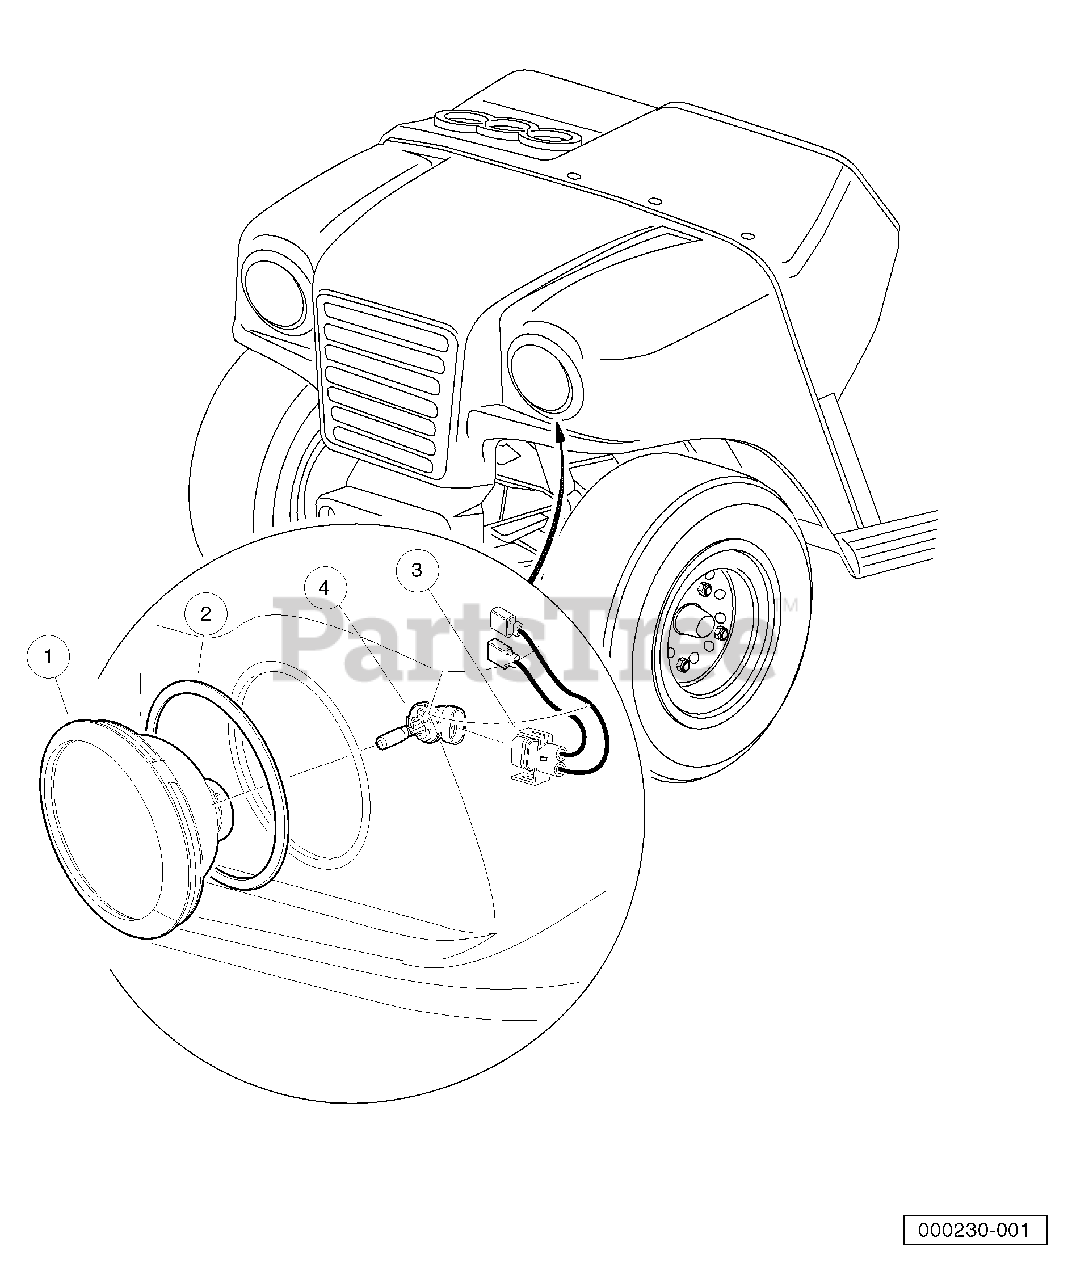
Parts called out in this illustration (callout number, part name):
1	Assembly, Headlight
2	Spacer, Headlight, Oval
3	Harness, Headlight
4	Bulb, Headlight, Oval
